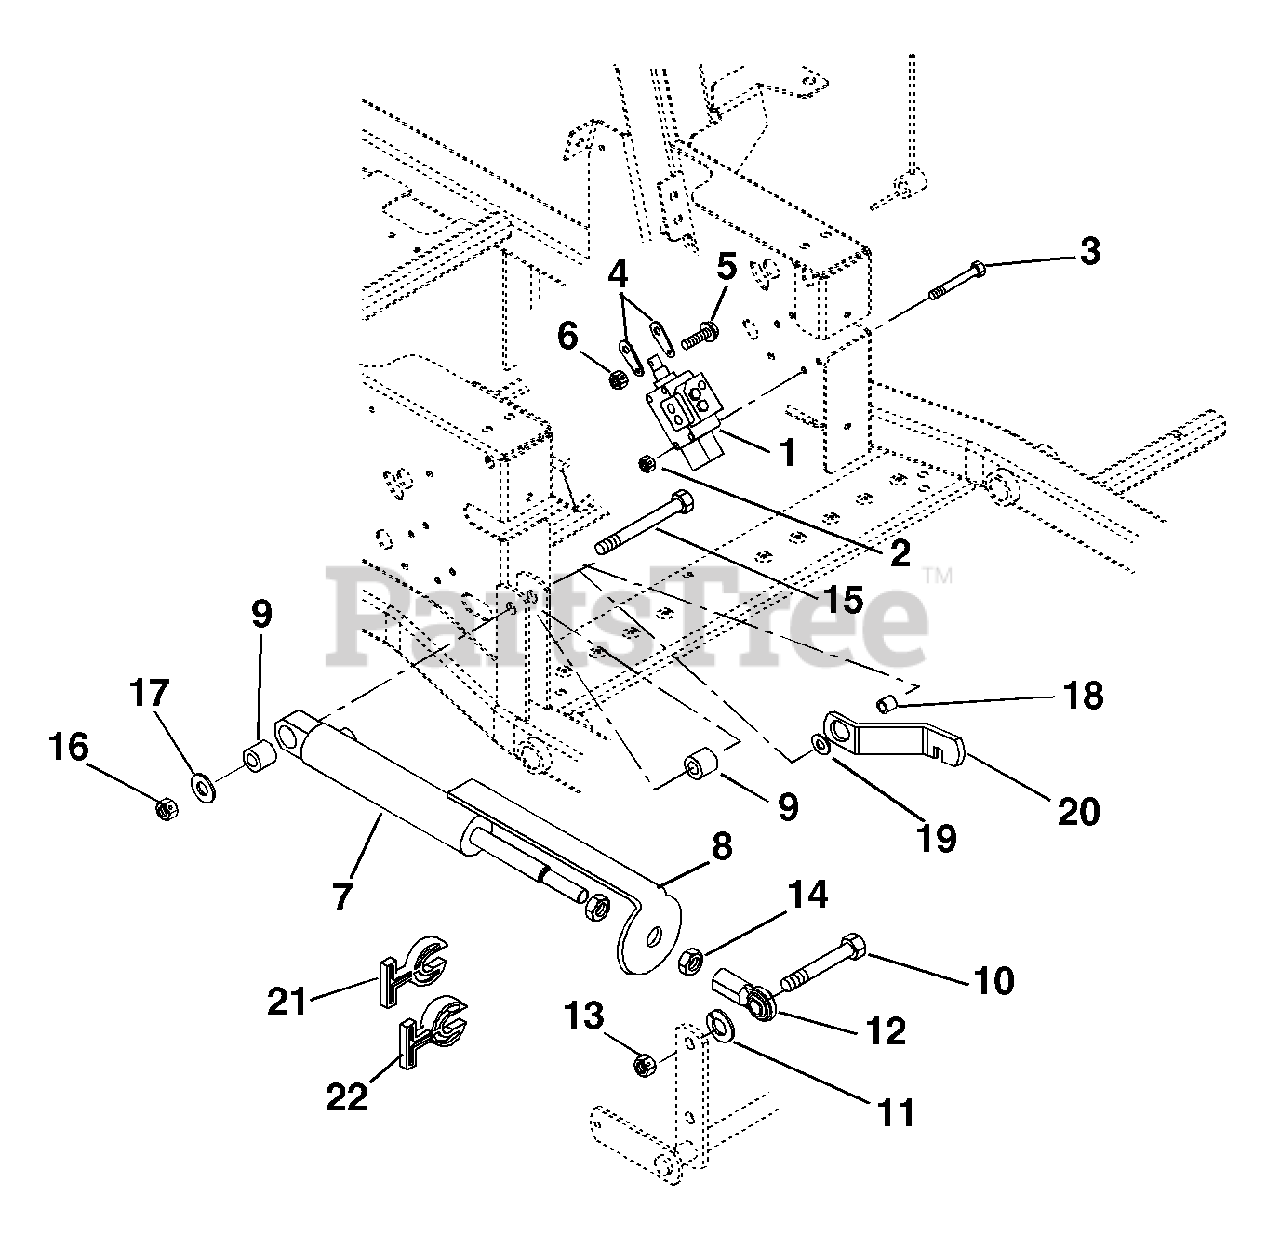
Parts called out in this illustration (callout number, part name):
1	Valve, Hydraulic Lift
2	Nut-Locking-Nylon .25-20
3	Bolt-Hex .25-20 x 2.75 Grade 5
5	Screw-Machine 10-24 x 1.00 Hex Washer Head
6	Nut-Locking-Nylon 10-24 with Insert
7	Cylinder-Hydraulic Lift
8	Strap-Height of Cut Indicator
9	Bushing .516 x 1.000 x 1.050
10	Bolt-Hex .62-11 x 2.25 Grade 8
11	Washer-Lock .62 x .156
12	Rod End-Right Hand-Female 5/8
13	Nut-Locking-Center .62-11
14	Nut-Jam .625-18
15	Bolt-Hex .50-13 x 3.75 Grade 5
16	Nut-Locking-Center .50-13
17	Washer-Flat-Steel .515 x 1.625 x .25
18	Bushing-Flange .515 x .75 x .275 x 1.12
19	Wave-Washer .76 x 1.12 x .08
21	Stop, Cylinder .34 Thick
22	Stop, Cylinder .68 Thick
